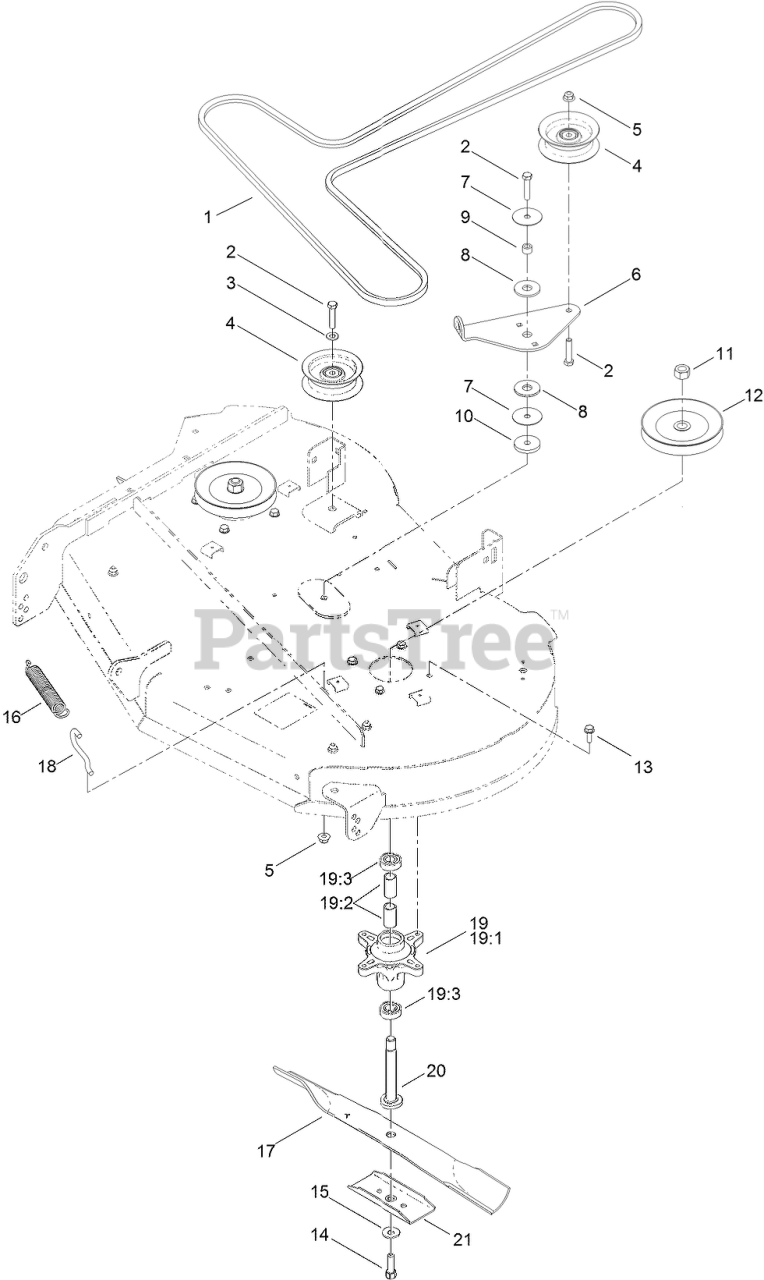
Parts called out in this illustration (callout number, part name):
1	V-BELT
2	SCREW-HH
3	WASHER-FLAT
4	PULLEY-IDLER, FLAT
5	NUT-HF, NI
6	ARM-IDLER
7	WASHER
8	WASHER-FRICTION, COMPOSITE
9	SPACER
10	SCREW-HH
11	NUT-HEX
12	Pulley
13	SCREW-TAPTITE
14	SCREW-HH
15	WASHER-BELLEVILLE
16	SPRING-EXTENSION
17	BLADE-21.6 INCH
18	HOOK-RETURN, SPRING
19	SPINDLE ASM
19:1	SPINDLE
19:2	SPACER
19:3	BEARING-BALL
20	SHAFT-SPINDLE
21	STIFFENER-BLADE
